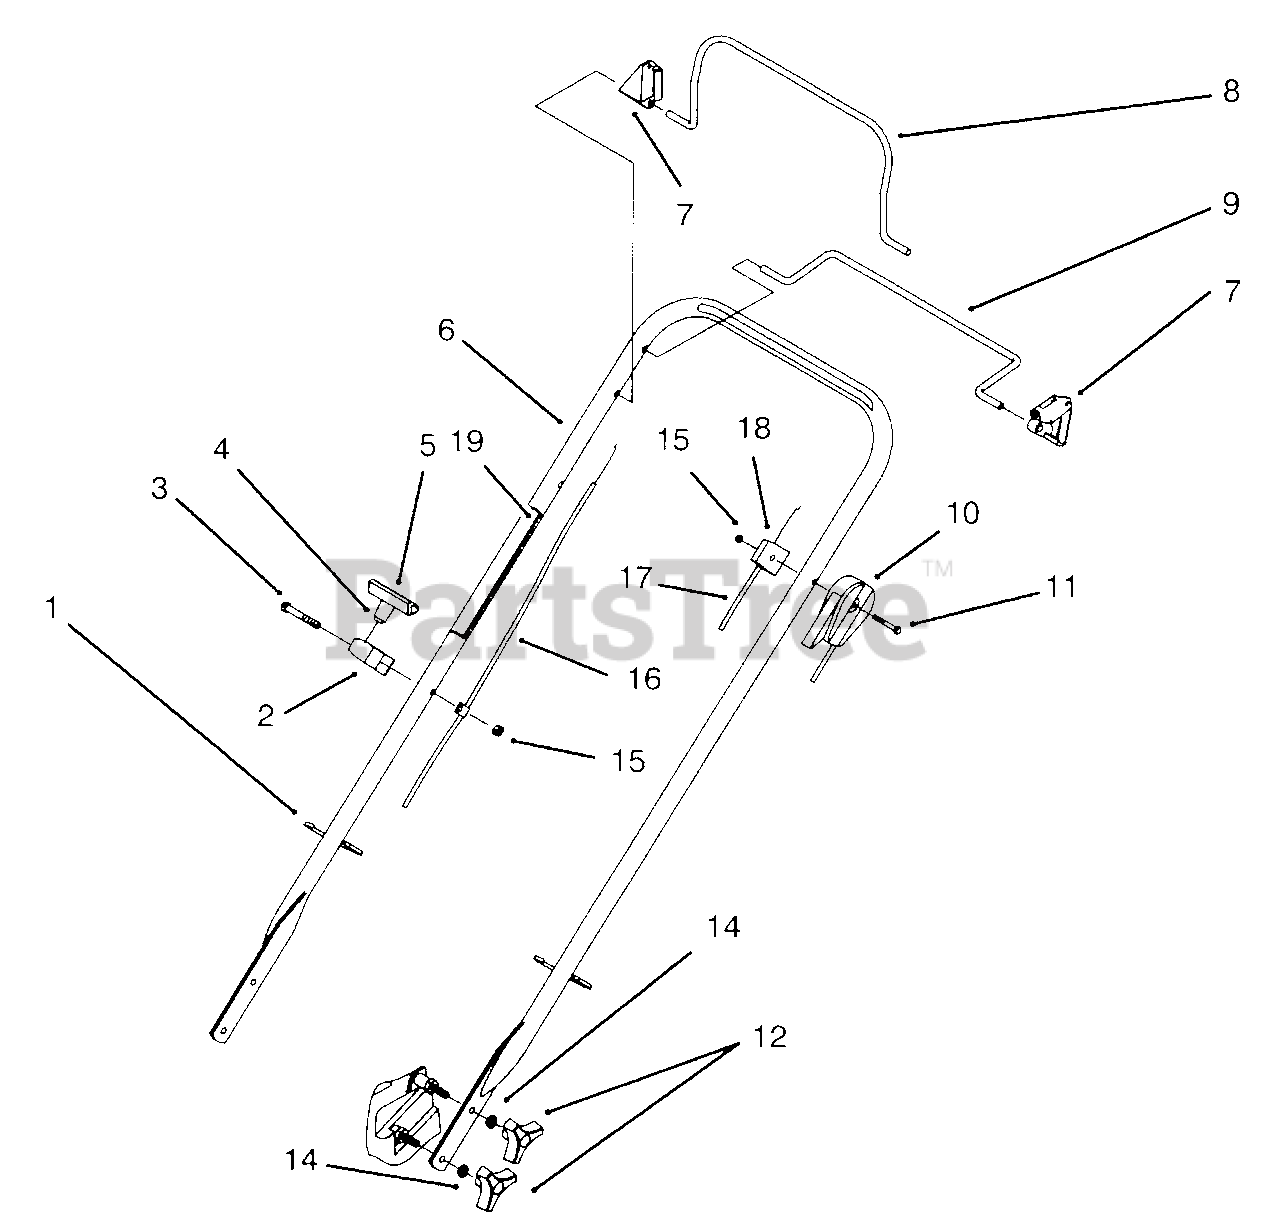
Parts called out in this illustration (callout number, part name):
1	Tie-Cable
2	Guide-Rope
3	Screw-Hex Hd. Cap
4	Handle-Starter
5	Clip-Rope Insert
7	Stop-Pivot
8	Bail-Flywheel Brake
9	Bail-S.P. Control
10	Cable-Throttle
11	Screw-Hex Hd. Cap
12	Knob
14	Washer-Lock
15	Nut-Lock Insert
16	Cable-Brake
17	Cable-Traction
18	Anchor-Cable S.P. Upper
19	Decal-Operation
